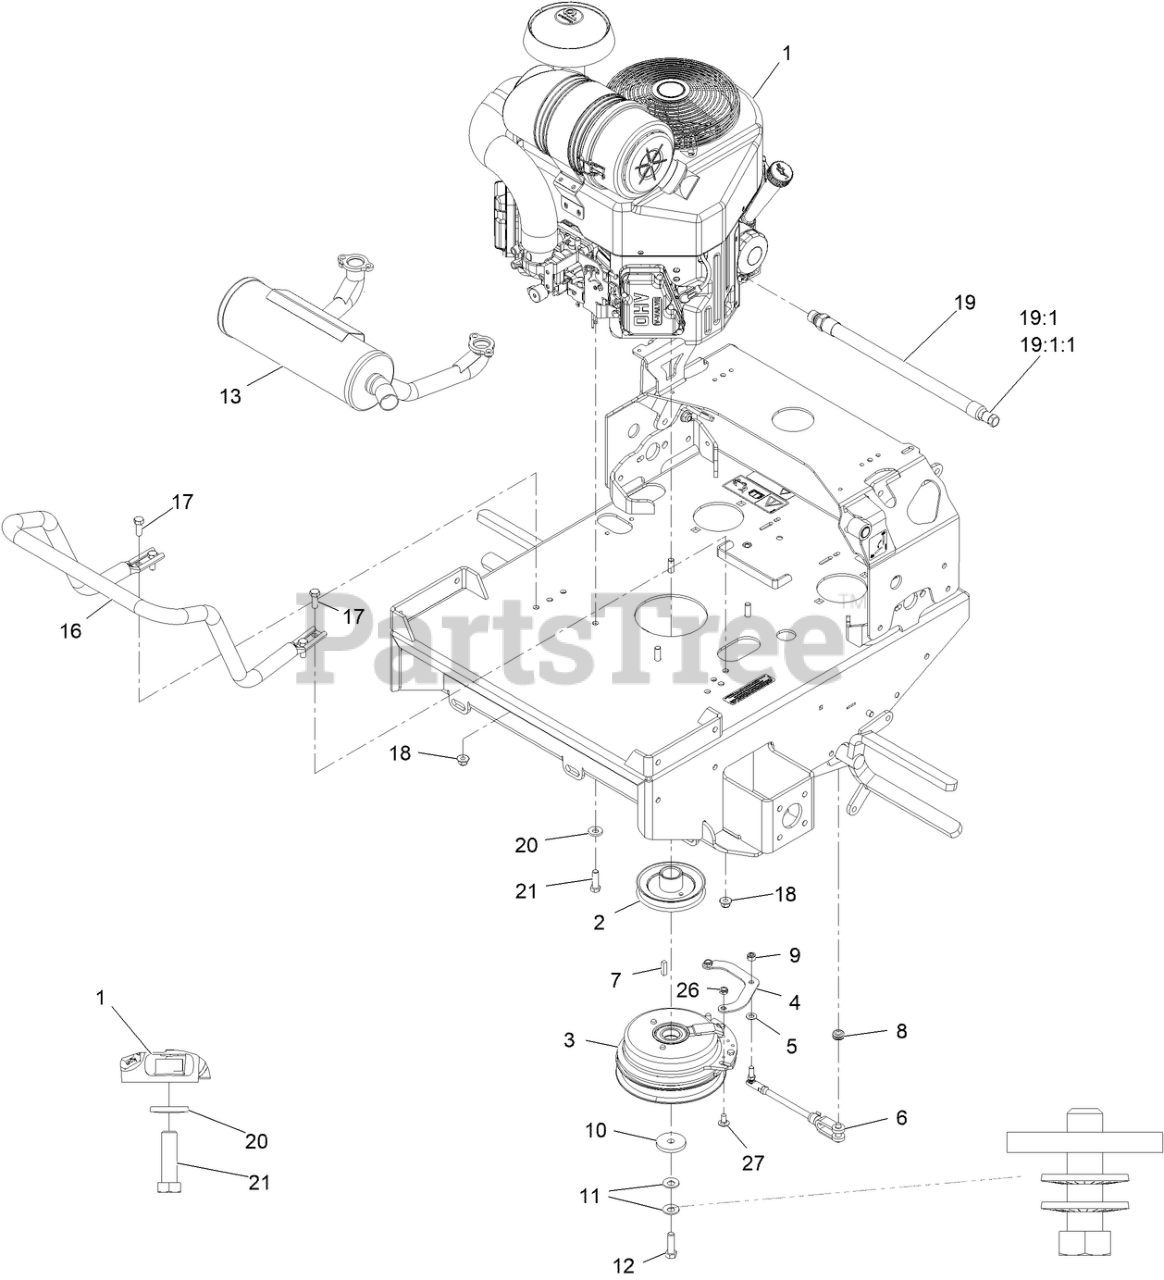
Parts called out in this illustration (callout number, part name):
2	SHEAVE W/ HUB
3	CLUTCH, 200 FT/LBS, 1.13
4	STRAP, CLUTCH
5	WASHER-PLAIN
6	ASM, CLUTCH ANCHOR
7	KEY
8	GROMMET
9	NUT-LOCK
10	WASHER-CLUTCH
11	WASHER-SPRING
12	BOLT-HEX, TAP
13	MUFFLER,HORIZONTAL
16	TUBE-GUARD MUFFLER
17	SCREW-HH
18	NUT-HF, NI
19	ASM, ENGINE OIL DRAIN HOS
19:1	PLUG-HH
19:1:1	O-RING
20	WASHER-BELLEVILLE
21	SCREW-HH
26	NUT-LOCK, NI
27	SCREW-CARR
